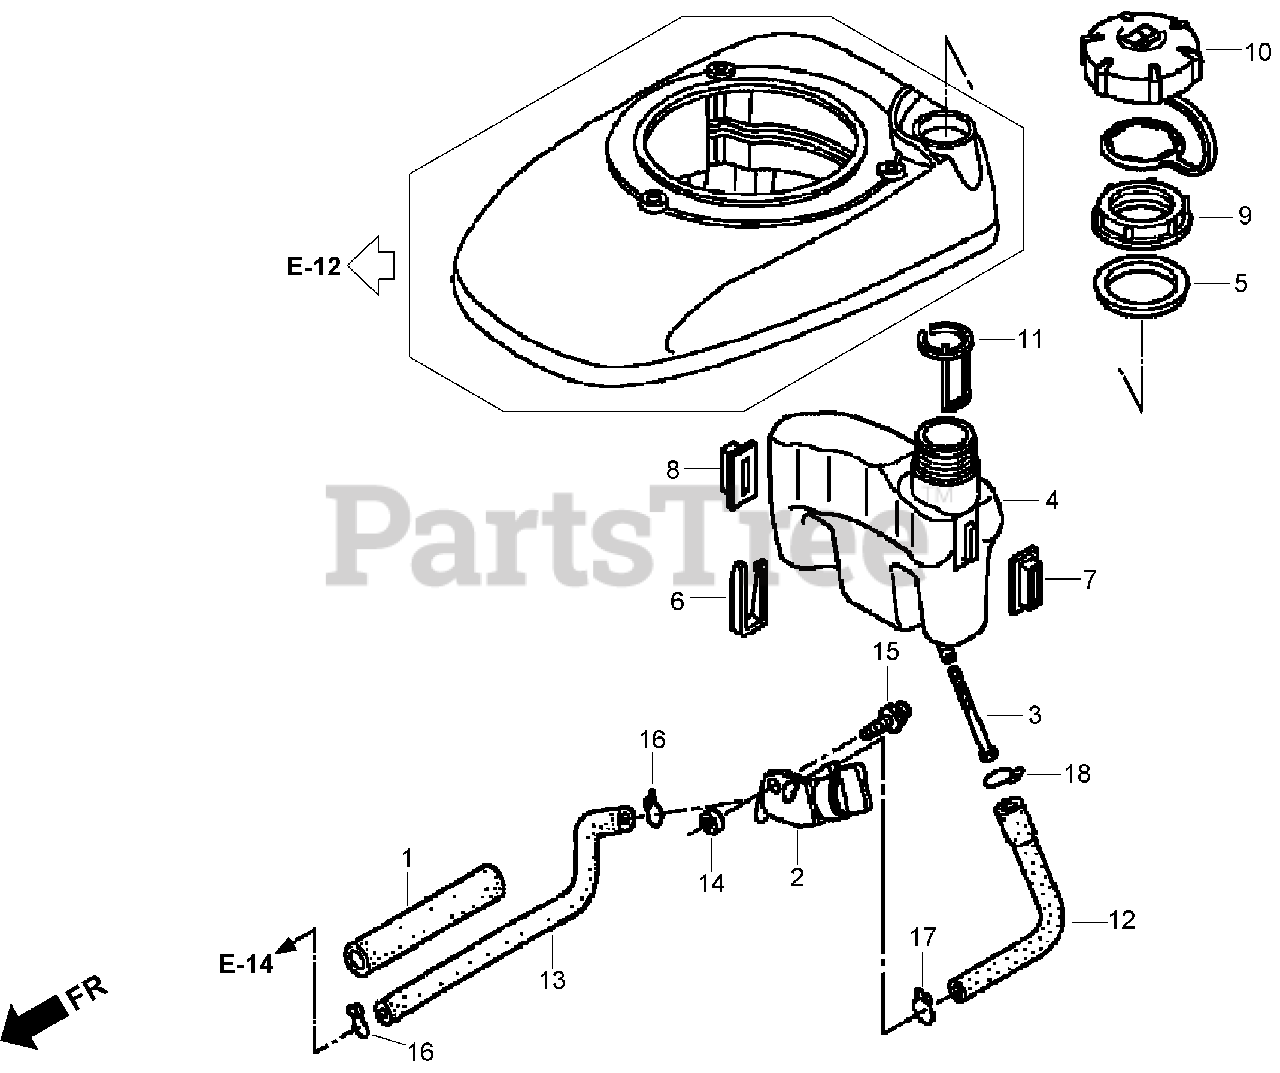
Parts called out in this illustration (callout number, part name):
1	SUPPORTER-RUBBER (107 mm)
2	PETCOCK ASM
3	FILTER-FUEL
4	TANK-FUEL
5	SEAL-NECK, FUEL FILLER
6	CLIP-MOUNTING, TANK
7	RUBBER A-MOUNTING, TANK
8	RUBBER B-MOUNTING, TANK
9	NUT-MOUNTING, TANK
10	FUEL TANK CAP ASM
11	GAUGE-LEVEL, FUEL
12	TUBE-TANK, FUEL
13	TUBE-FUEL
14	COLLAR-PETCOCK, FUEL
15	SCREW-WASHER (5X10)
16	CLIP-TUBE (B8)
17	CLIP-TUBE (B10)
18	CLIP-TUBE (C11)
